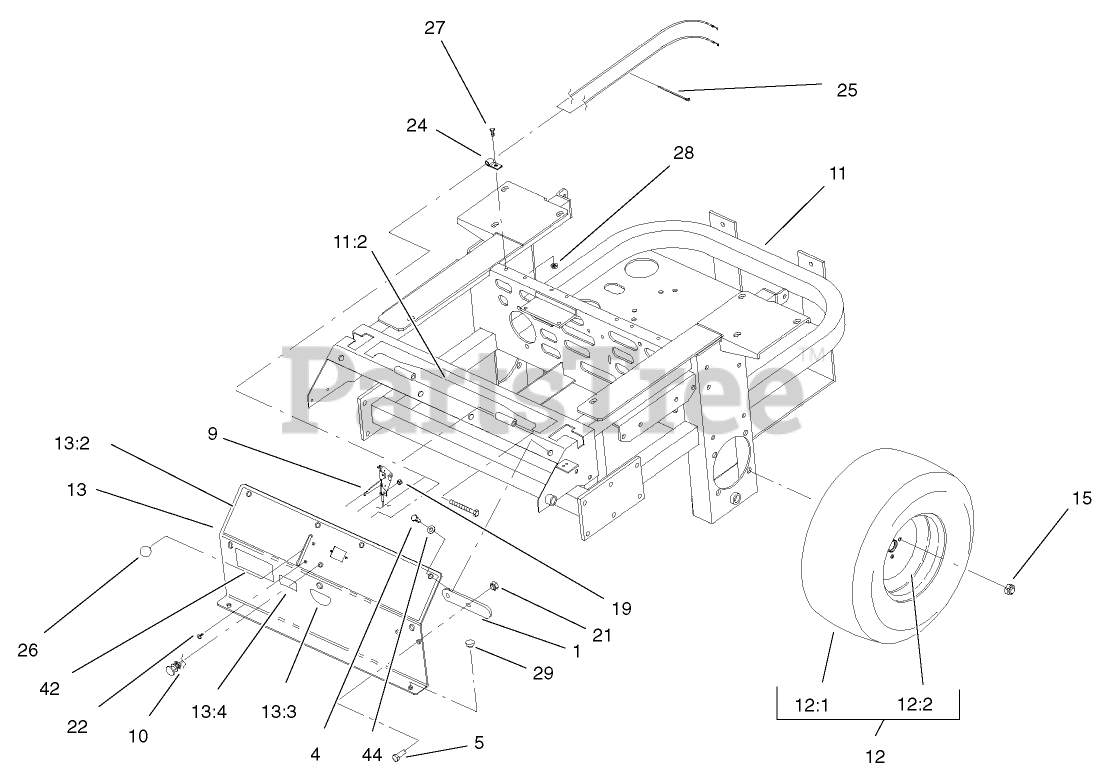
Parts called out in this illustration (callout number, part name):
1	Stop-Park Brake
2	Seat-Suspension
3	DECAL-EFI
4	SCREW-HH
5	SCREW-HH
6	Track-Locking
9	Cable
11	Frame ASM-Rear
11:2	Decal-Battery
11:3	Decal-Motion Control
11:4	Decal-Drive Release
11:5	Decal Hazardous Mat.
12	Wheel & Tire ASM
12:1	Tire
12:2	Wheel
13	CONSOLE ASM
13:2	DECAL-PANEL, CONTROL
13:3	Decal, Fuel Valve-Dual
13:4	DECAL-PROTECTION, EAR
14	Frame-Seat
15	Nut
16	Rod-Seat Holdup
17	SCREW-HH
18	SCREW-HH
19	NUT-LOCK, NI
20	NUT-LOCK NI
21	NUT-LOCK, NI
22	Bolt-CARR
23	NUT-HF
24	Clip
25	Tie-Plastic
26	Knob
27	SCREW-HH
28	NUT-HF
29	Bumper
30	CLAMP-R
31	SCREW-HWHTF
33	TUBE-MANUAL
34	DECAL
42	DECAL-Z256E
44	WASHER-PLAIN
47	Spacer-Stop,Seat
